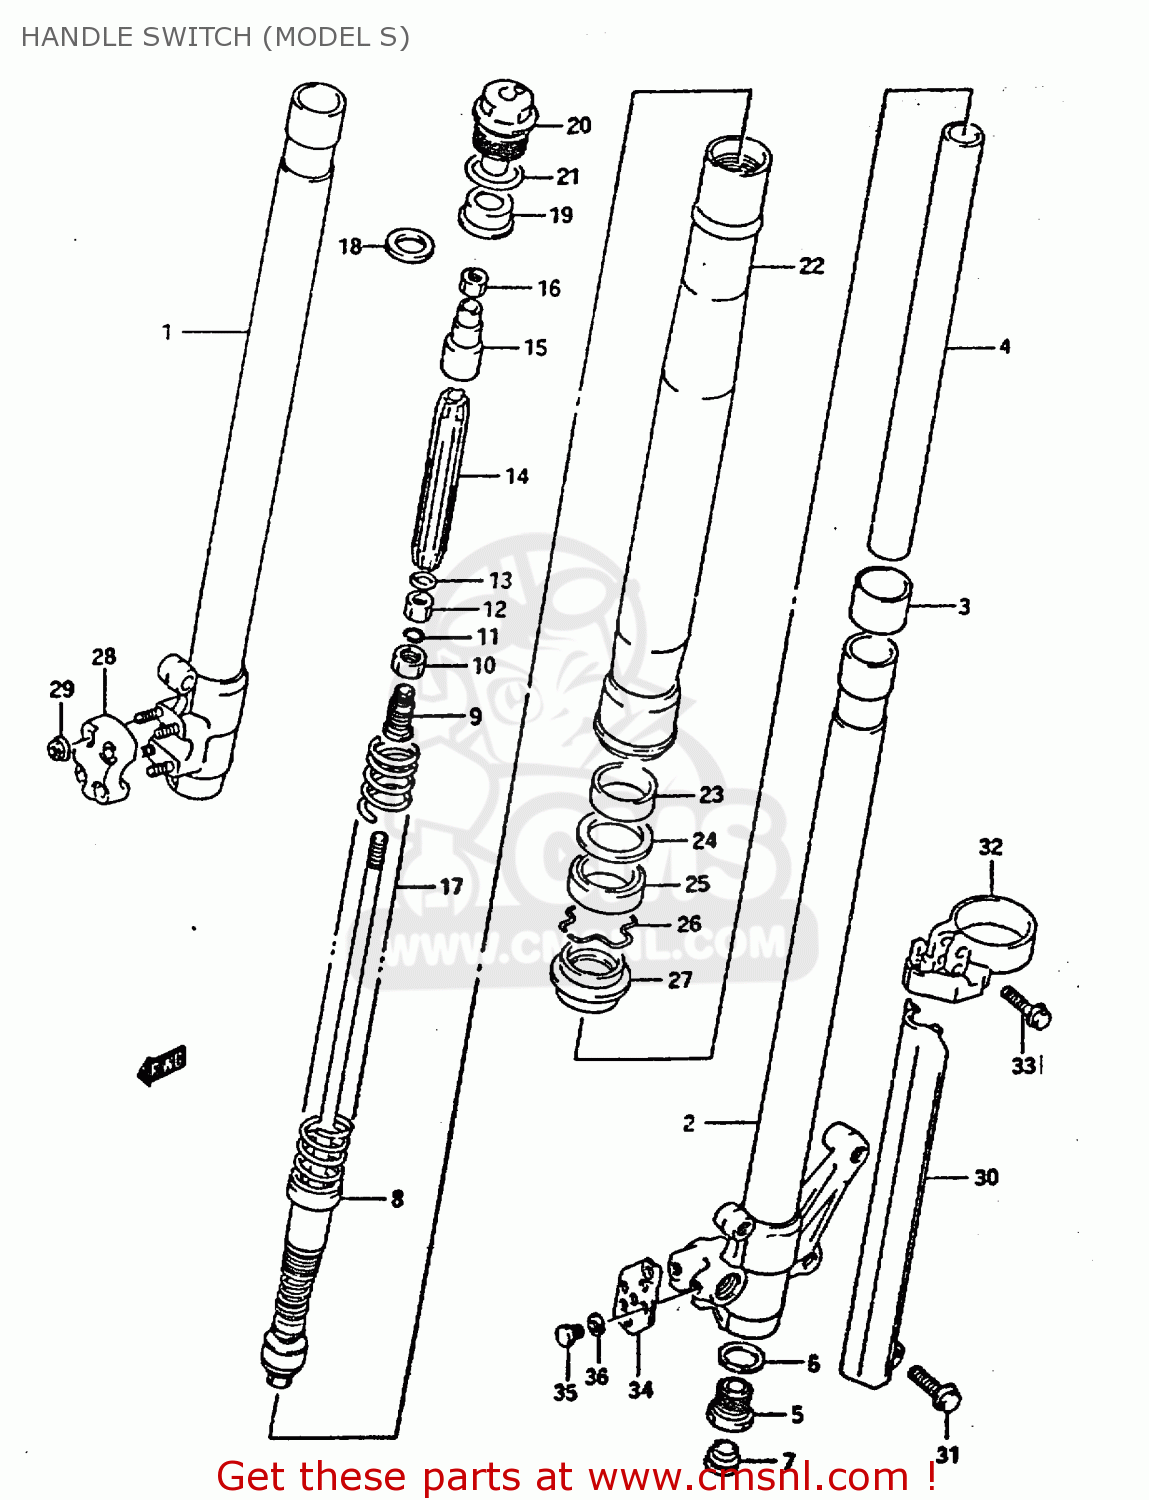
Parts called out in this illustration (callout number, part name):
1	GRIP,THROTTLE
2	CASE ASSEMBLY,THROTTLE
3	ROTOR,THROTTLE
4	BOLT 6X25
5	SCREW,UPPER
6	SCREW
7	COVER,THROTTLE CASE
8	LEVER,BRAKE
9	BOLT,BRAKE LEVER
10	NUT,BRAKE LEVER
11	BOLT,ADJUST
12	NUT ,5MM
13	SPRING,RETURN
14	COVER,BRAKE LEVER
15	GRIP,L
16	LEVER ASSEMBLY,CLUTCH
17	LEVER,CLUTCH
18	BOLT,LEVER
19	NUT 6MM
20	ADJUSTER,WIRE
21	NUT,LOCK
22	BOLT
23	HOLDER,CLUTCH LEVER
24	COVER,CLUTCH LEVER
25	COVER,CLUTCH LEVER
